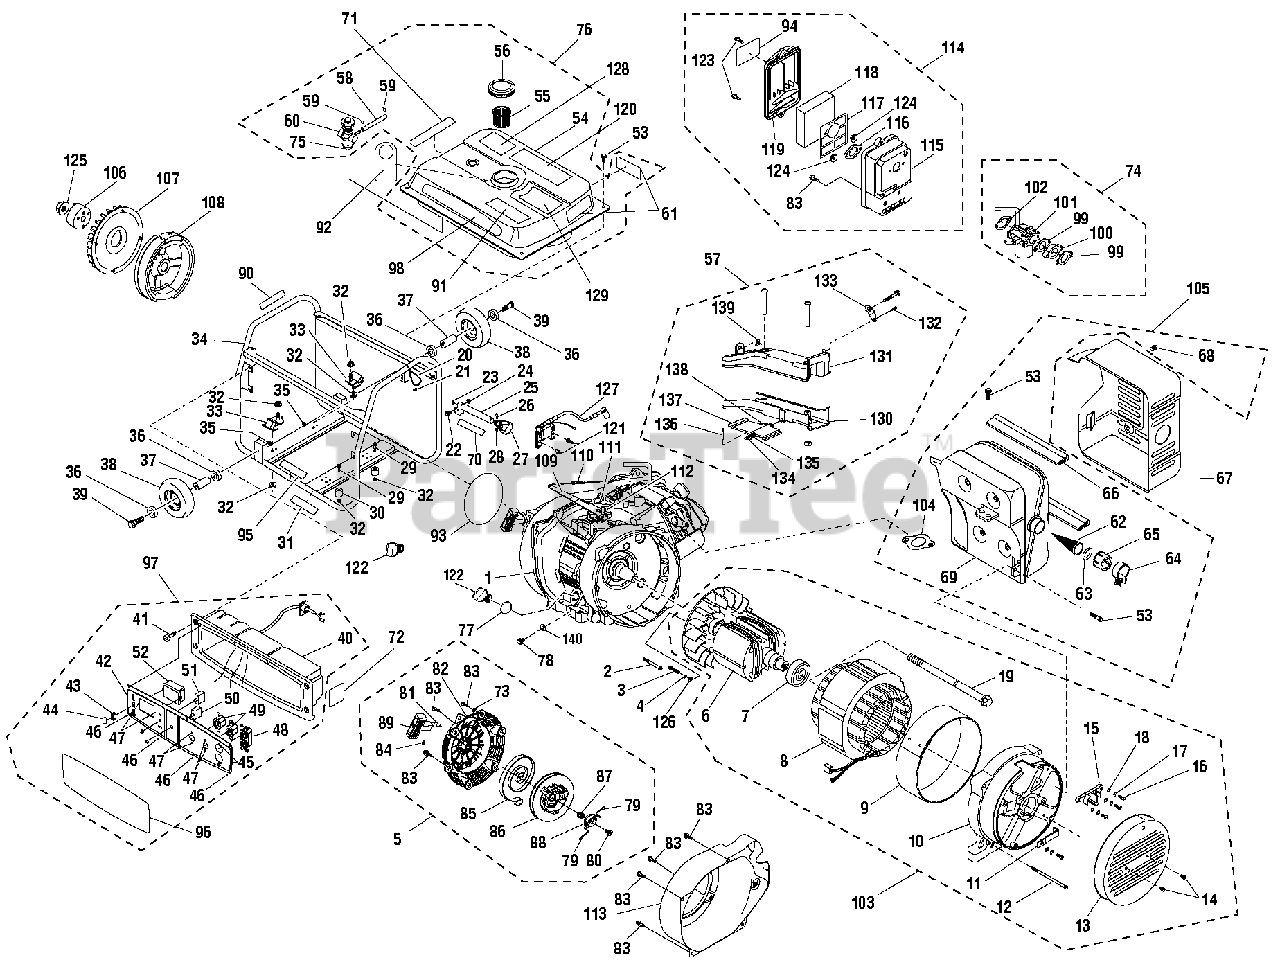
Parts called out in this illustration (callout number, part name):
1	Engine SPE195
2	Bolt (M8 x 35 mm)
3	Bolt (M6 x 12 mm)
5	Recoil Stator Assembly
6	Rotor Assembly
8	Stator Assembly
9	Stator Cover
10	Rear Frame
11	Wire Compressing Plate
12	Bolt (M6 x 103 mm) (88)
13	Rear End Cover
14	Bolt (M6 x 10 mm)
15	Wire Rack
16	Screw (M5 x 14 mm)
17	Lock Washer (M5)
18	Washer (M5)
22	Bolt (M8 x 40 mm)
23	Handle Stem Head
24	Lock Nut (M8)
26	Square Bolt
29	Screw (M8 x 40 mm)
30	Alternator Vibration Absorber
31	Combustion Warning Label
33	Engine Vibration Absorber
35	Lock Nut (M10 x 1.25 in.)
36	Wheel Bushing
37	Axis Cover
39	Bolt (M10 x 75 mm)
40	Control Box
41	Screw (M6 x 14 mm)
42	Control Panel
43	Engine Switch
44	Switch Jacket
45	Bolt (M3.5 x 9 mm)
46	Bolt (M3.9 x 9 mm)
47	Bolt (M4 x 8 mm)
48	120 V 20 Amp Receptacle
49	120 V 30 Amp Receptacle
50	AC Circuit Breaker (20 A)
51	AC Circuit Breaker (25 A)
52	4 in 1 Digital Meter
53	Bolt (M6 x 12 mm)
54	Fuel Tank
55	Fuel Strainer
56	Fuel Tank Cap
57	Air Conduct Assembly
58	Fuel Hose
59	Fuel Hose Clip
60	Fuel Cock
61	Hot Surface Label
62	Muffler Screen
65	Muffler Screen Cover
66	Shockproof Bar
67	Muffler Cover
68	Bolt (M6 x 10 mm)
70	Locking Pin Label
71	Start Guide Label
72	Ground Label
73	Bushing Block
74	Carburetor Assembly
76	Fuel Tank Assembly
77	Oil Filler Seal
78	Drain Plug (M10 x 1.25-16 )
82	Starter Case
83	Screw (M6 x 12 mm)
84	Rope Clip
85	Starter Spring
86	Drum Sheave
88	Pawl Guide
89	Starter Handle
90	Fire Danger Label
91	Ground Warning Label
92	Oil Hangtag
93	Engine Shround Logo
94	Choke Label
95	Lubricant Label
96	Control Panel Label
97	Control Panel Assembly
98	Logo Label
101	Carburetor
103	Alternator Assembly
104	Exhaust Gasket
105	Muffler Assembly
106	Starting Hub
109	Governor Arm
111	Carburetor Spring
114	Air Cleaner Assembly
115	Air Filter Case
117	Element Fitting Plate
118	Air Filter Element
119	Air Filter Cover
120	Warning Label
121	Screw (M6 x 20 mm)
122	Oil Cap/Dipstick
123	Screw (M6 x 12 mm, Fillister Hd.)
125	Nut (M16, Flange Hd.)
127	Ignition Module
128	CPSC Label
129	Danger Label (Fr)
130	Warm Air Tube Hypotheca
131	Warm Air Tube Epitheca
132	Bolt (M4.8 x 16 mm)
133	Connector
136	Cotter Pin
137	Valve Plate
139	Elastic Nut (M44.8)
140	Drain Plug Gasket
